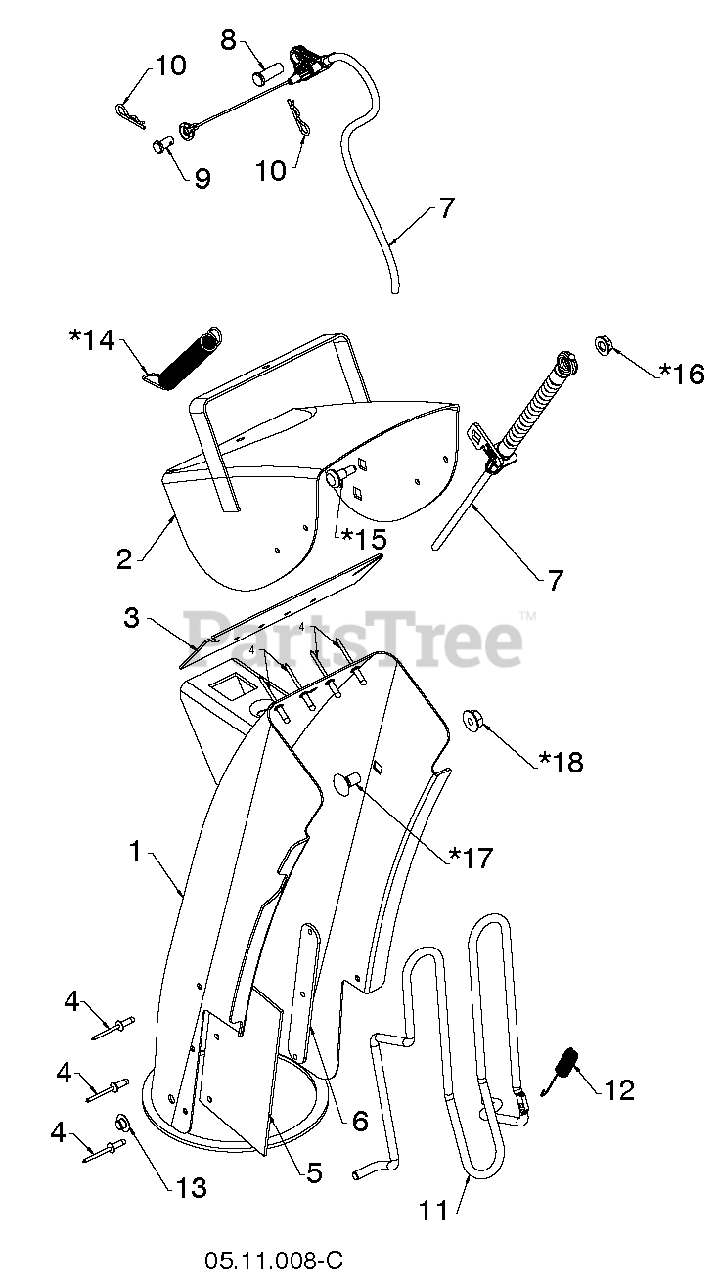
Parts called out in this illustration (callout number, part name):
1	RP_CHUTE.WELDMENT.SNOW.ORANGE
2	DEFLECTOR.WELDMENT.PNT.ORANGE
3	SEAL.DEFLECTOR
4	RIVET BLIND
5	SHIELD.SNOW.CHUTE
6	STRAP.SHEILD.RETAINER
7	CABLE CONTROL.CHUTE.DEFL.BOWDE
8	PIN CLEVIS 5/16X.875
9	PIN CLEVIS .25 X .31
10	HAIRPIN.SOFT.ZINC.059X1.125
11	ROD.GUARD.CHUTE (2 2)
12	SPRING.CHUTE.GUARD
13	NUT
14	SPRING.DEFLECTOR.REM.CHUTE
15	BOLT SHOULDER 1/4
16	NUT.HEX.LRG.FLANGE.1/4-20.LOCK
17	BOLT CAR BLK 5/16-18 X 5/8
18	NUT.HEX.FLANGE.LOCK.5/16-18
